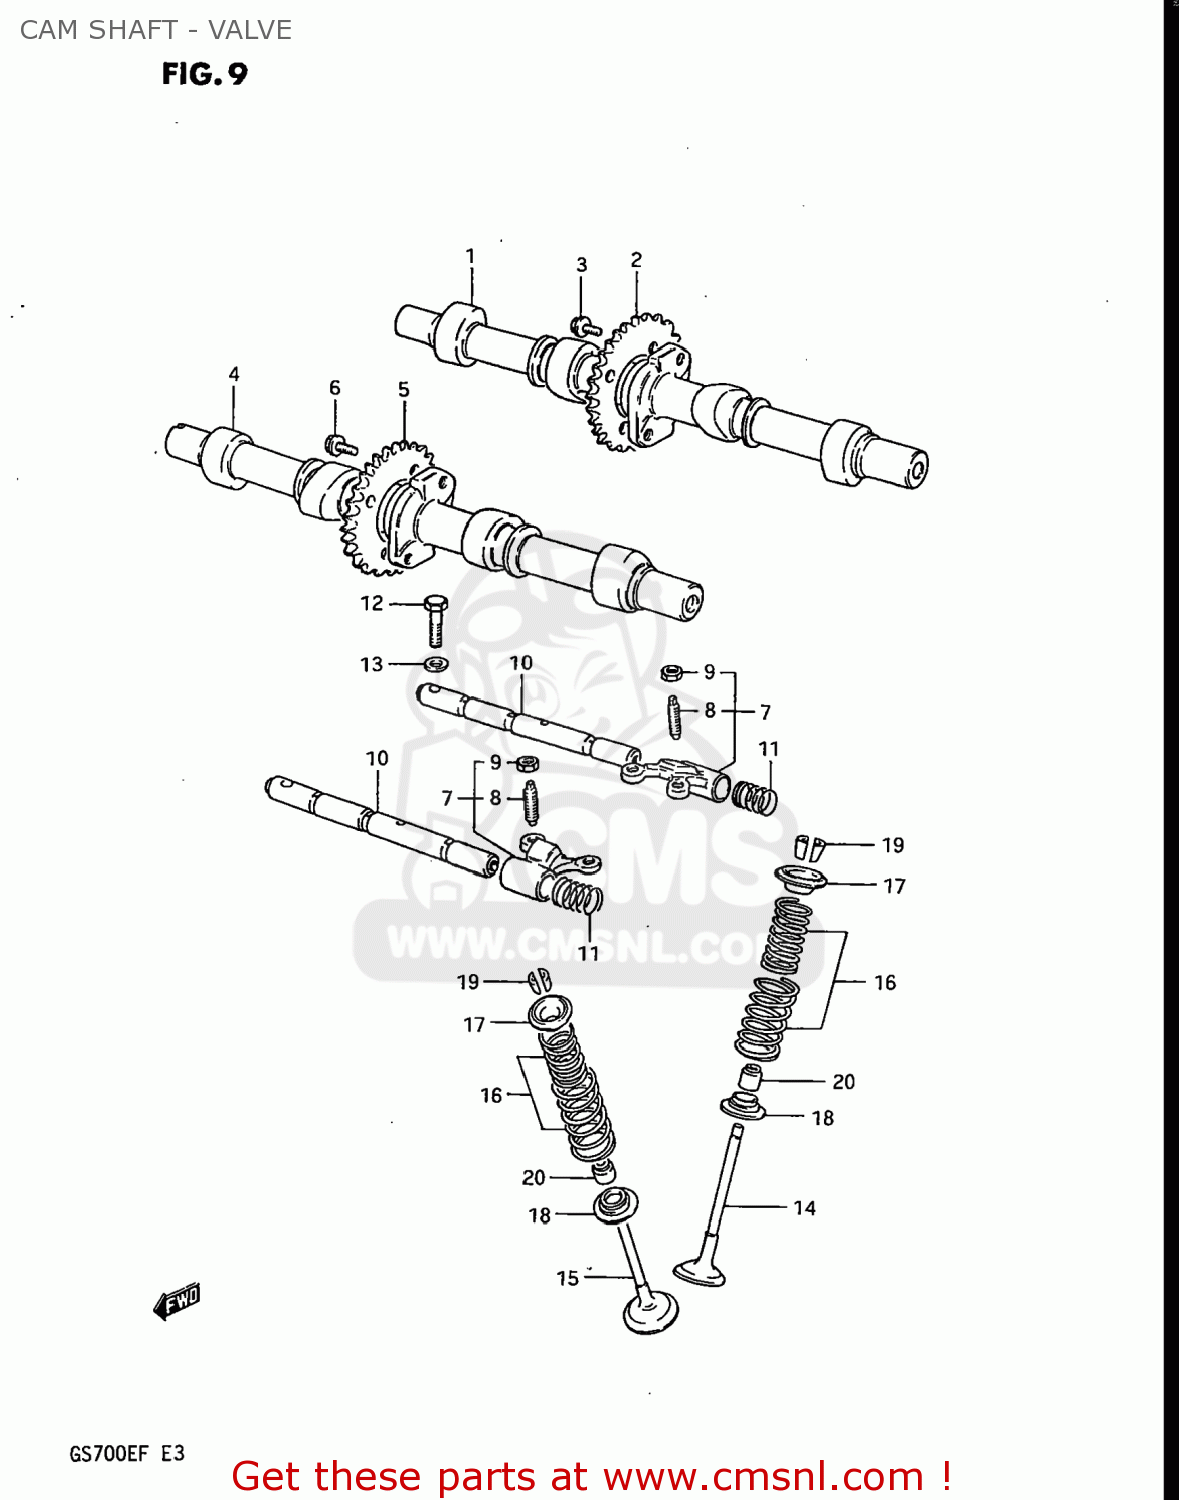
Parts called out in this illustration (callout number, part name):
1	CAMSHAFT,INTAKE
2	SPROCKET,INTAKE CAMSHAFT
3	BOLT(7X11)
4	CAMSHAFT,EXHAUST
5	SPROCKET,EXHAUST CAMSHAFT
6	BOLT(7X11)
7	ARM,VALVE ROCKER
8	SCREW,TAPPET ADJUSTING
9	NUT,ADJUSTING
10	SHAFT,VALVE ROCKER
11	SPRING
12	BOLT
13	WASHER, LOWER
14	VALVE,INTAKE
15	VALVE,EXHAUST
16	SPRING SET,VALVE
17	RETAINER,VALVE SPRING
18	SEAT,VALVE SPRING
19	COTTER VALVE
20	OIL SEAL
